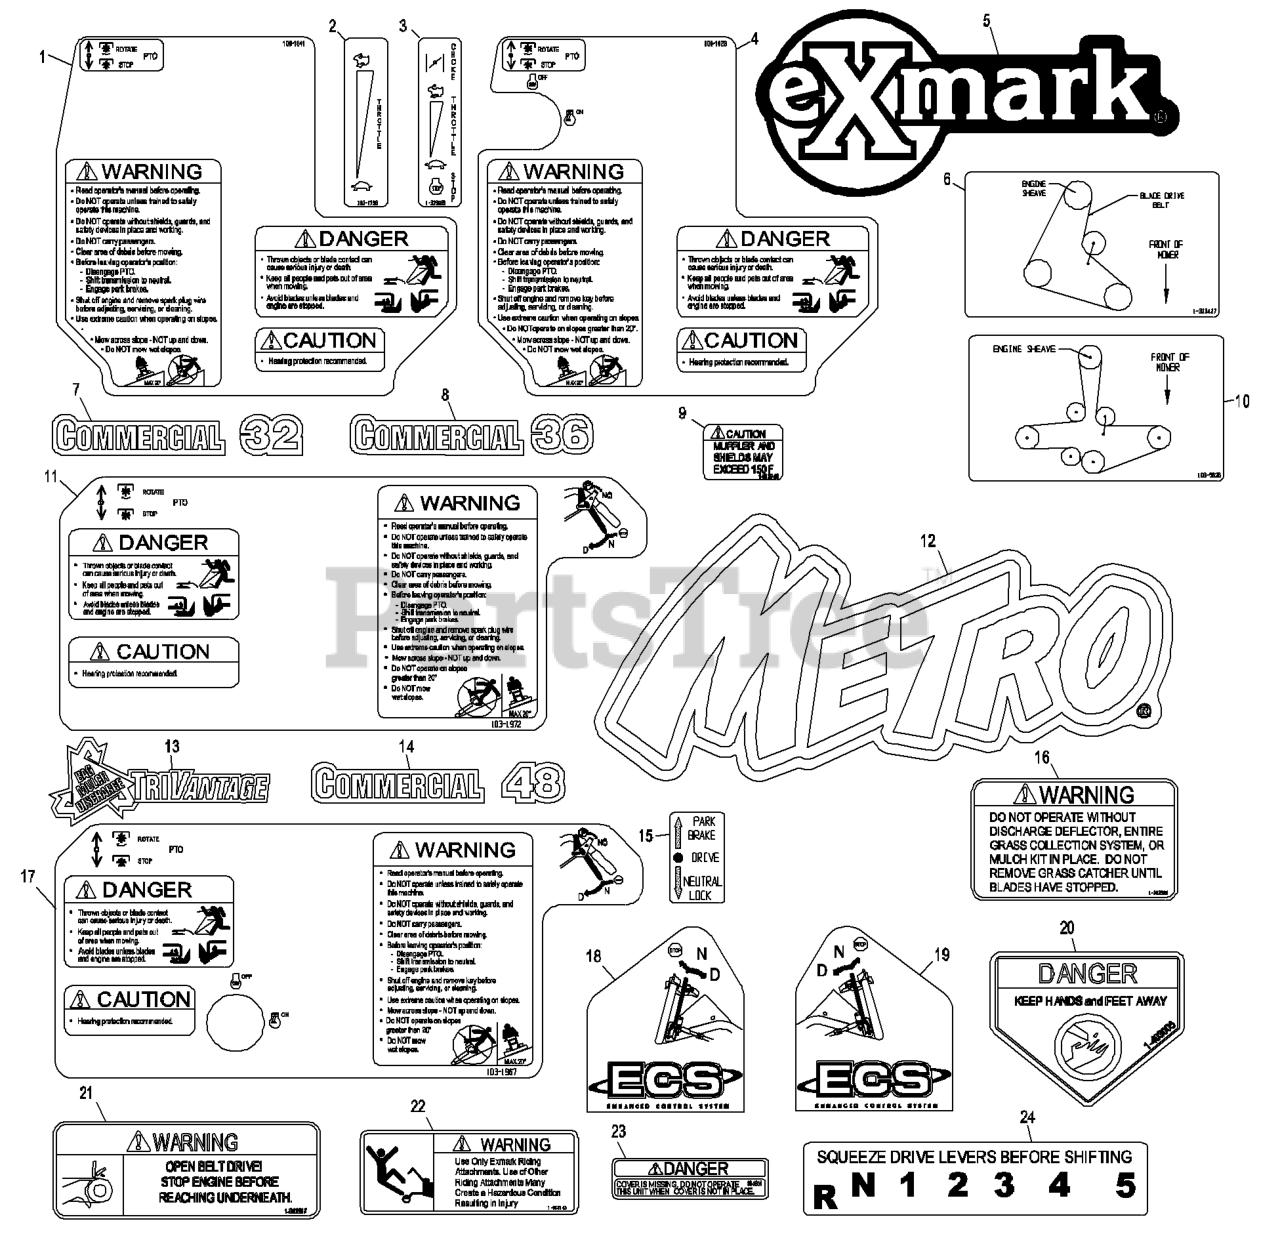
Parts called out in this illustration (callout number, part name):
1	DECAL,METRO ECS CONSOLE
2	DECAL,THROTTLE ONLY
4	DECAL,METRO ECS CONSOLE
5	DECAL,EXMARK LOGO
6	DECAL,BELT ROUTING 32/36
7	DECAL,COMMERCIAL 32
8	DECAL,COMMERCIAL 36
10	DECAL,BELT ROUTING
11	DECAL,CONSOLE
12	DECAL,METRO MODEL
14	DECAL,COMMERCIAL 48
15	DECAL,NEUTRAL/BRAKE
16	DECAL-WARNING, DISCHARGE
17	DECAL,CONSOLE
18	DECAL,RH ECS INSTRUCTION
19	DECAL,LH ECS INSTRUCTION
20	DECAL-DANGER
21	DECAL,BELT DRIVE
22	DECAL,SULKY WARNING
23	DECAL-COVER, MISSING
24	DECAL,SHIFTER
